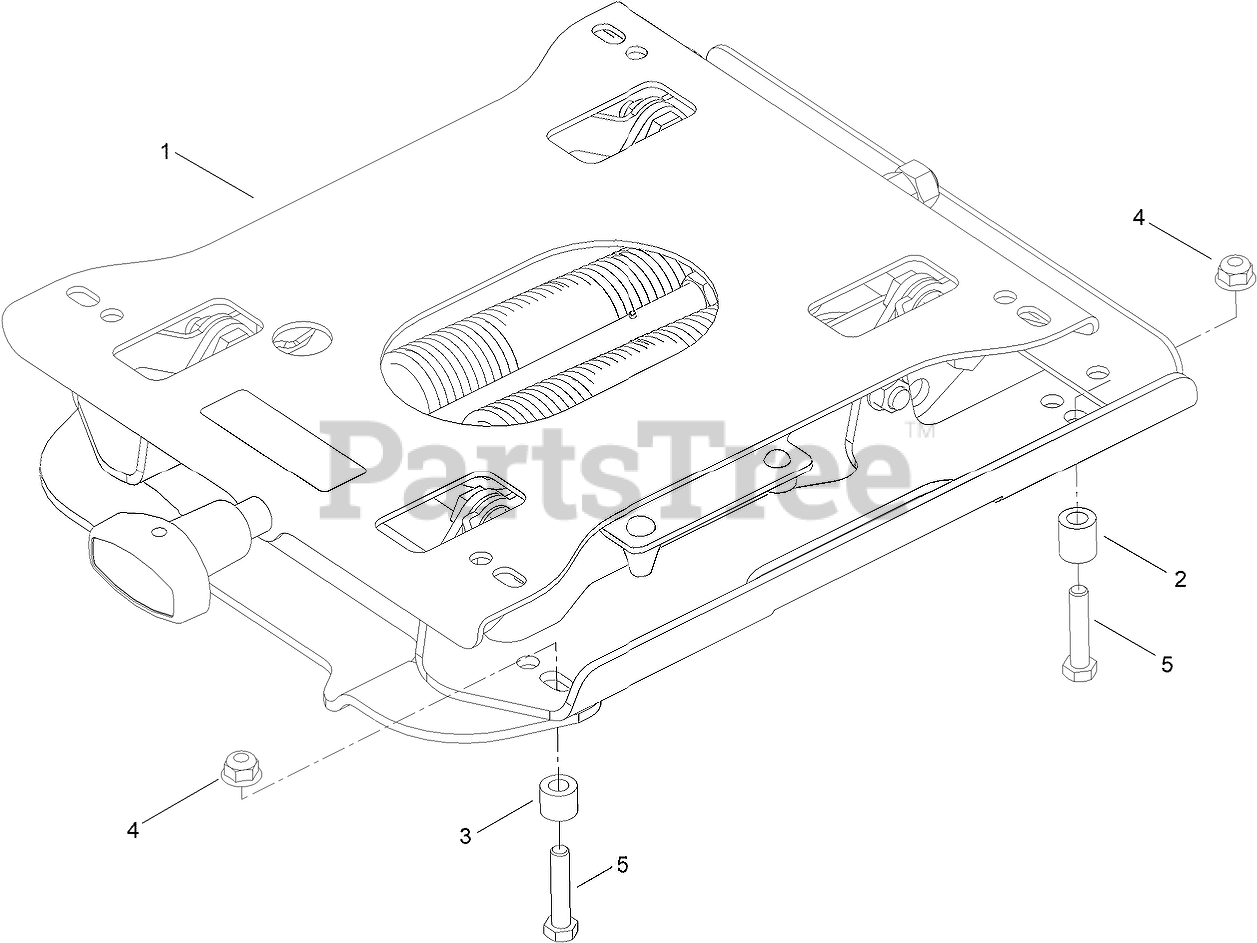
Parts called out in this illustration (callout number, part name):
1	SEAT-SUSPENSION
2	SPACER
3	SPACER-TUBE
4	NUT-HF, NI
5	SCREW-HH
